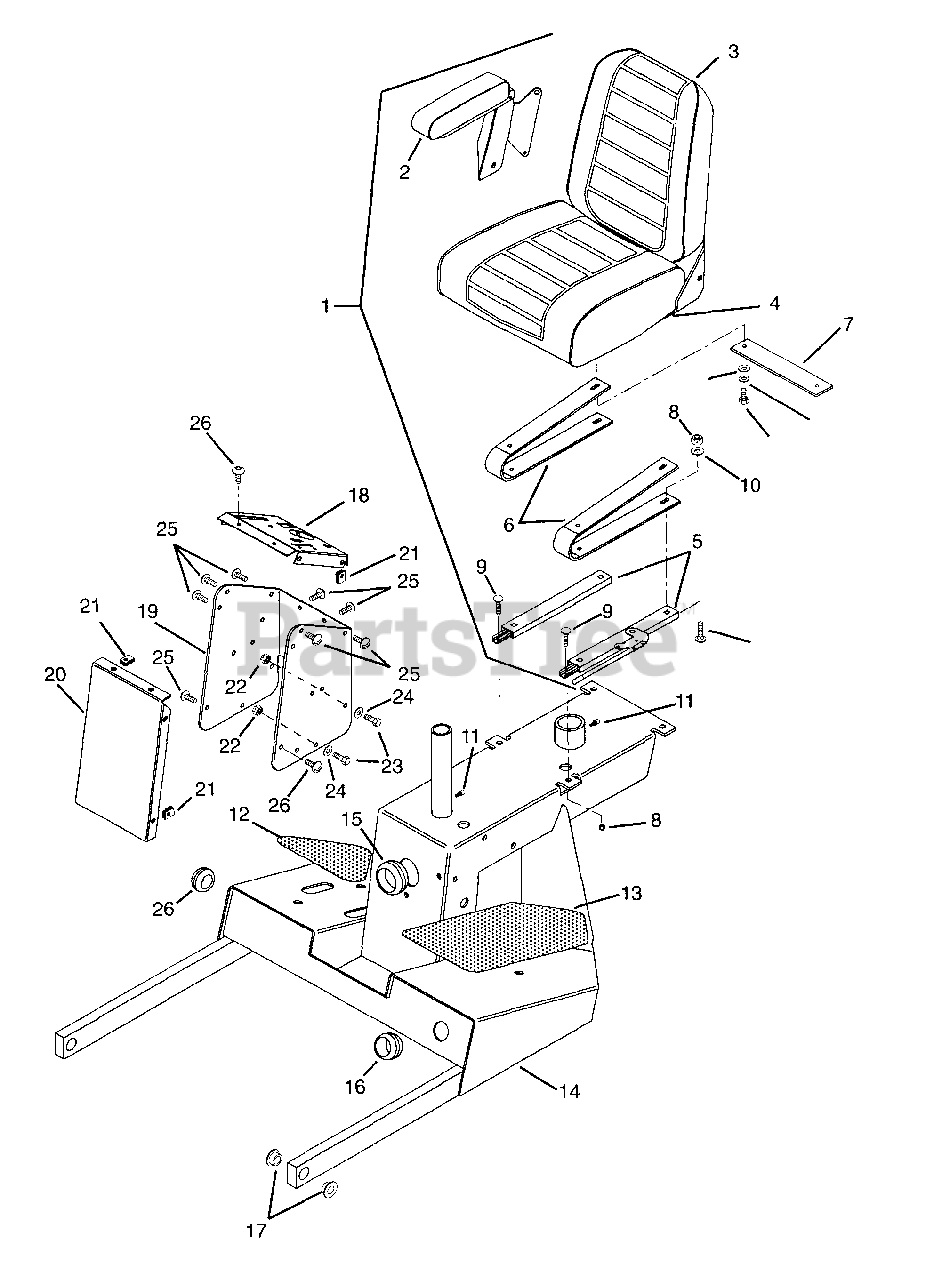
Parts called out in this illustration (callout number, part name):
1	Assembly-Seat
2	Arm Rest-Right Hand
2	Arm Rest-Left Hand
3	Cushion-Back
4	Seat Cushion w/Switch
5	Seat Slides with Handle
6	Spring-Seat
7	Bracket-Seat
8	Nut-Locking-Center .31-18
9	Bolt-Round Head Square Neck .31-18 x 1.00 Grade 5
10	Washer-Flat-Steel .344 x .688 x .065
11	Fitting-Lube .25-28 x .256
12	Cover-Footboard Right Hand
13	Cover-Footboard Left Hand
14	Weldment-Rear Frame
15	Grommet
16	Grommet 1.50 x 1.75 x 2.12
17	Bushing-Flange .762 x 1.0 x .580 x 1.48
18	Panel-Instrument
19	Panel-Support Instrument Panel
20	Front Panel
21	Nut-Retainer .25-20 x .56
22	Nut-Locking-Center .25-20
23	Bolt-Hex .25-20 x 1.00 Grade 5
24	Washer-Flat-Steel .281 x .620 x .065
25	Screw-Machine .25-20
26	Grommet 1.25 x 1.5 x 1.81
